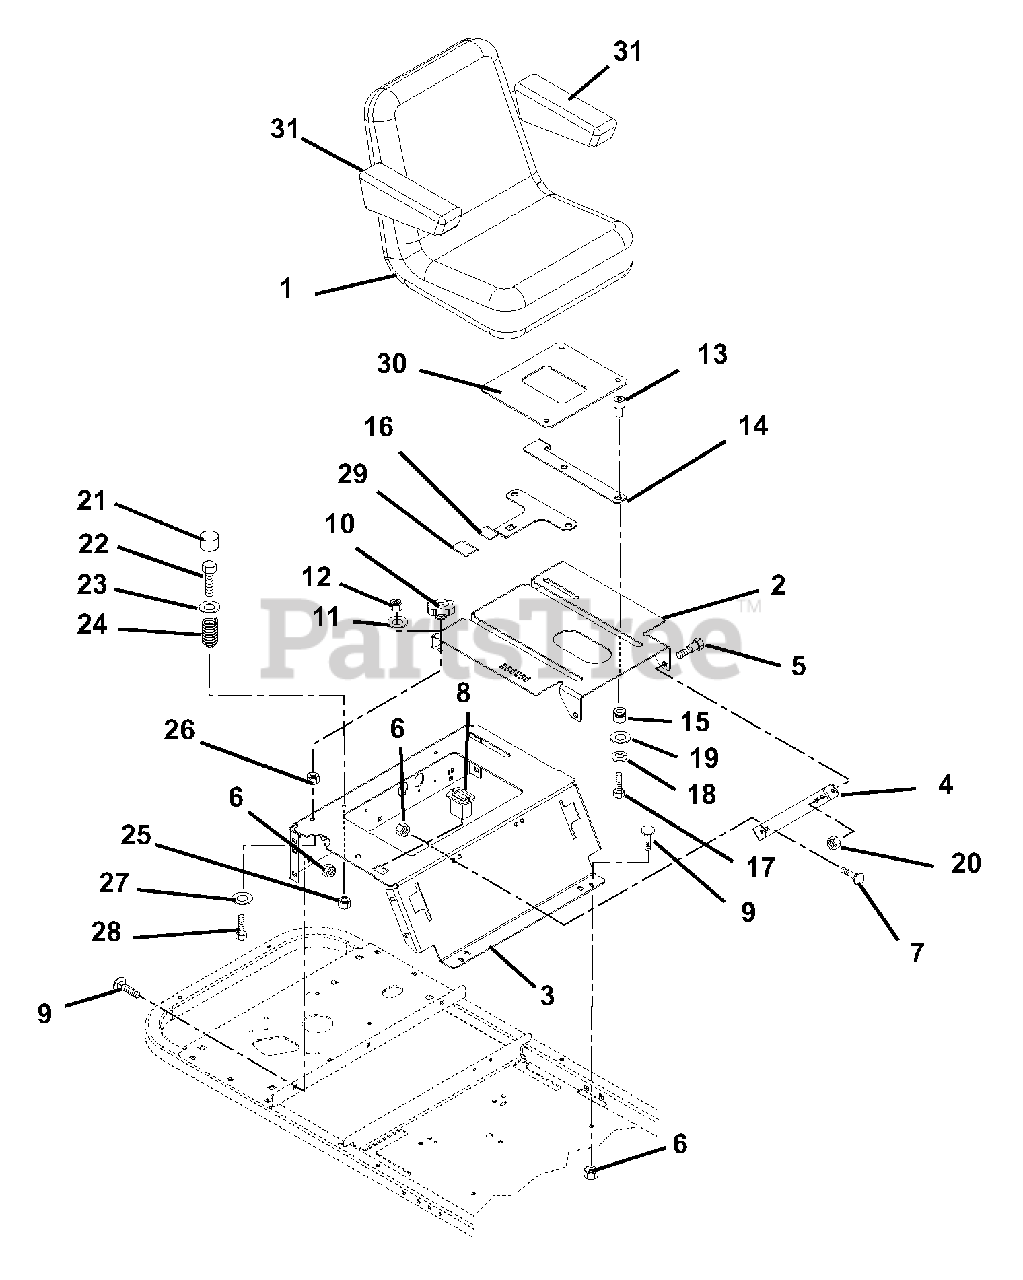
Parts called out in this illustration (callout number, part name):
1	SEAT, HIGH BACK 2805 SERIES
2	SEAT PLATE
3	SEAT BOX
4	BRACKET, SEAT PLATE
5	BOLT-SHLDR .375-16X.150
6	@NUT-LK-NYL-FLG .38-16 YWZC
7	@BLT-RDHDSQNK .38-16X1.00 G5YZ
8	HOURMETER-QUARTZ 80VDCMAX
9	@BLT-RDHDSQNK .38-16X1.00 G5YZ
10	KNOB-CLAMPING, .312-18 NYLOC
11	WSHR-FL-STL .328X1.0X.094 YWZC
12	@NUT-LK-NYL .312-18 YWZC
13	SPACER, SEAT TOP
14	SEAT STOP
15	SPACER, SEAT BOTTOM
16	LEVER, SEAT ADJUSTMENT
17	@BLT-HEX .31-18X2.25 GR5 YWZC
18	@WSHR-LK .31X.078 REG YWZC
19	WSHR-FL-STL .344X1.375X.075YWZ
20	@NUT-LK-TOP-FLG .38-16 YWZC
21	HUB CAP
22	@BLT-HEX .31-18X1.00 GR5 YWZC
23	WSHR-FL-STL .328X1.0X.094 YWZC
24	SG. COMP 2.9L X 2.02OD 200LB
25	@NUT-LK-NYL-FLG .31-18 YWZC
26	@NUT-SPNLK-FLG .312-18 YWZC
27	WSHR-FL-STL .505X1.00X.062YWZC
28	@BLT-RDHDSQNK .31-18X3.50 G5YZ
30	SEAT SUPPORT PLATE
31	ARMREST KIT
